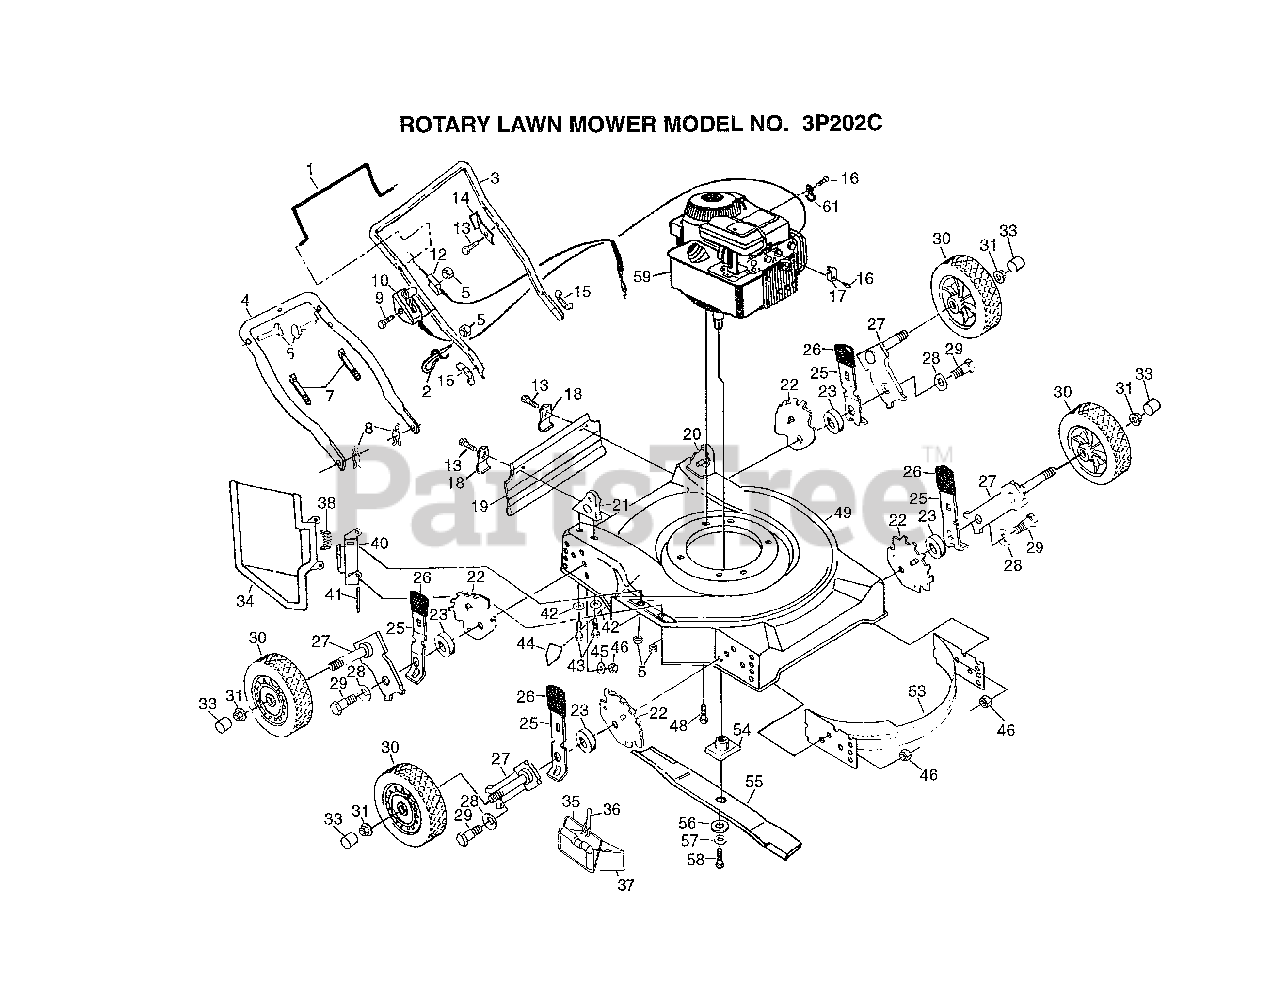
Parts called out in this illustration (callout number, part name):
1	CONTROL BAR PM
2	ROPE GUIDE
6	BOLT.HANDLE.LM
8	HAIRPIN COTTER
9	SCREW.HXHD.WASH.
10	CONTROL THROTTLE
12	"CABLE,ENG ZONE CO"
13	TAPPING SCREW
14	"BRKT,UPSTOP"
15	"NUT,WING PM"
16	SCREW PM
17	CABLE CLAMP
18	"BRKT,DEFL PM"
19	SKIRT.REAR.FGD.22
22	BRACKET.WHL.ADJ.9
25	SPRING SELECTOR
26	KNOB PM
27	ARM.AXLE.ASM.BZP.
28	"WASHER, BELLEVIL."
29	BOLT SHLD 3/8-16
30	WHEEL.ASM
31	HEX FLANGE LOCKNT
33	HUB CAP-PLASTIC
34	GUARD.DISCH.22SD.
35	BAIL.PLUG.MUL.22.
36	LATCH.PLUG.22SD
40	BRACKET.HINGE.W/F
41	ROD.HINGE.COMBI-C
42	STEEL WASHER
43	SCREW
44	DECAL HYT
46	LOCKNUT PM
48	SCREW
49	KIT.HSG.22SD.PUSH
53	BAFFLE.FRT/REAR
54	BLADE ADAPTOR
55	"BLADE.MULCH.22"""
56	"WASHER,HARDEN"
57	LOCKWASHER
58	SCREW
61	GUIDE CLIP PM
